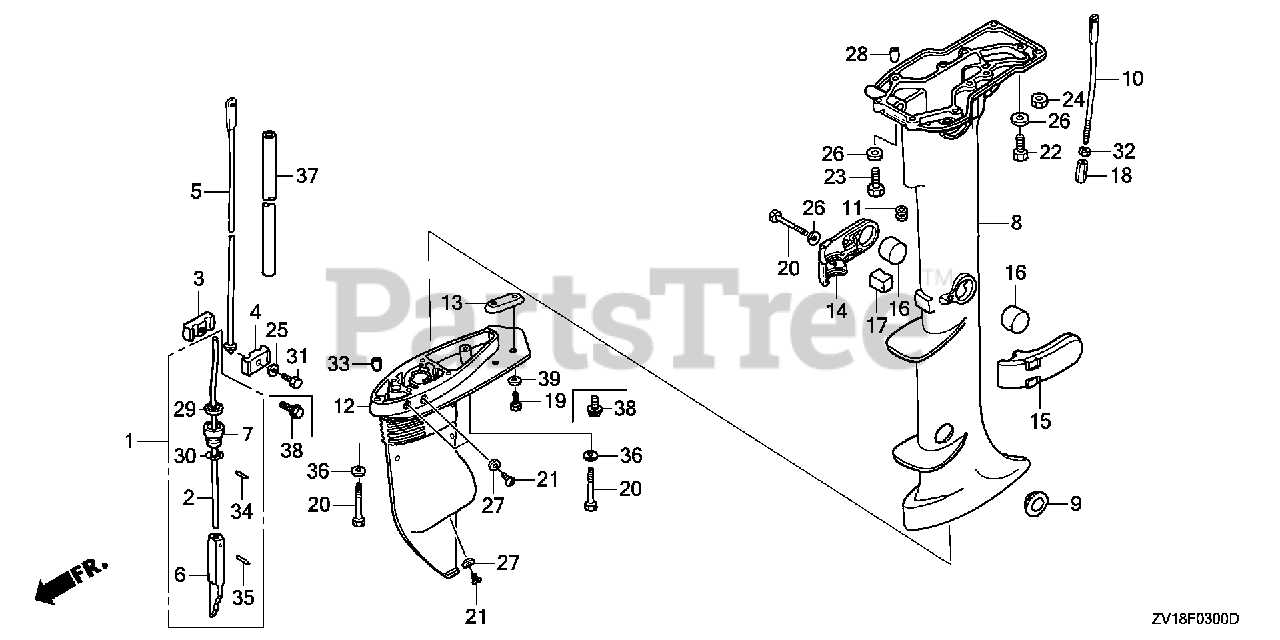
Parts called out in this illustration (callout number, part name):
1	ROD B, SHIFT
2	ROD B, SHIFT
3	JOINT, R. SHIFT ROD
4	JOINT, L. SHIFT ROD
5	ROD A, SHIFT (L)
7	HOLDER, SEAL
8	CASE, EXTENSION *NH282MU* (L) (OYSTER SILVER METALLIC-U)
9	GROMMET, EXTENSION
10	SHAFT, REVERSE LOCK
11	GROMMET, LOCK SHAFT
12	CASE, GEAR *NH282MU* (OYSTER SILVER METALLIC-U)
13	METAL, ANODE
14	HOUSING, R. MOUNTING (LOWER) *NH282MU* (OYSTER SILVER METALLIC-U)
15	HOUSING, L. MOUNTING (LOWER) *NH282MU* (OYSTER SILVER METALLIC-U)
16	RUBBER A, MOUNTING (LOWER)
17	RUBBER B, MOUNTING (LOWER)
18	NUT, REVERSE LOCK
19	BOLT, HEX. (6X18)
20	BOLT, HEX. (6X50)
21	BOLT, OIL CHECK
21	BOLT, OIL CHECK (8X8)
22	BOLT, HEX. (6X32)
23	BOLT, HEX. (6X40)
24	NUT, HEX. (6MM)
25	WASHER, PLAIN (6MM) Use from Frame SN 4800713.
26	WASHER, PLAIN (6MM) Use up to Frame SN 4800342.
27	WASHER, NYLON (8MM)
28	PIN, DOWEL (8X16)
29	SEAL, WATER (6MM)
30	O-RING (10.8X2.4) (ARAI)
31	BOLT, HEX. (6X16)
32	NUT, HEX. (5MM)
33	PIN A, DOWEL (8X14)
34	PIN, SPRING (2.5X10)
35	ROLLER (2.5X11.8)
36	WASHER, PLAIN (6MM) Use up to Frame SN 4800342.
37	BULK HOSE, FUEL (8X1000) (95001-80001-(95001-80001-60M)
38	BOLT, FLANGE (6X16) (SUS)
39	WASHER, PLAIN (6MM) Use up to Frame SN 4800342.
